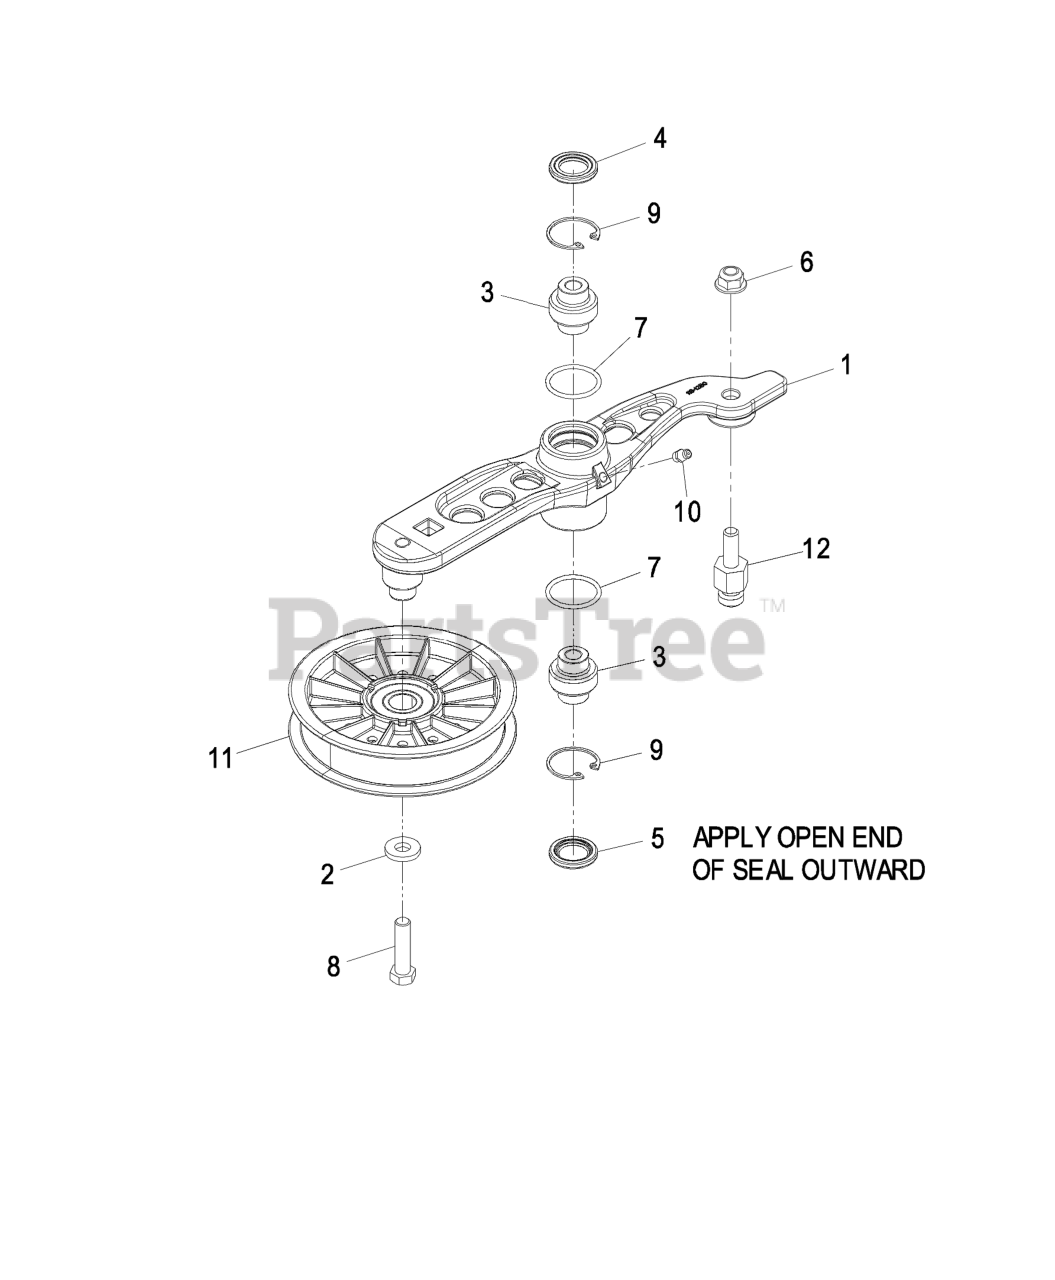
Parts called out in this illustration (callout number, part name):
3	BEARING-SPHERICAL
4	SEAL-LIP, DOUBLE
5	SEAL-LIP, SINGLE
6	NUT-HF, NI
8	SCREW-HH
9	RING-SNAP
10	FITTING-GREASE
11	PULLEY-IDLER
